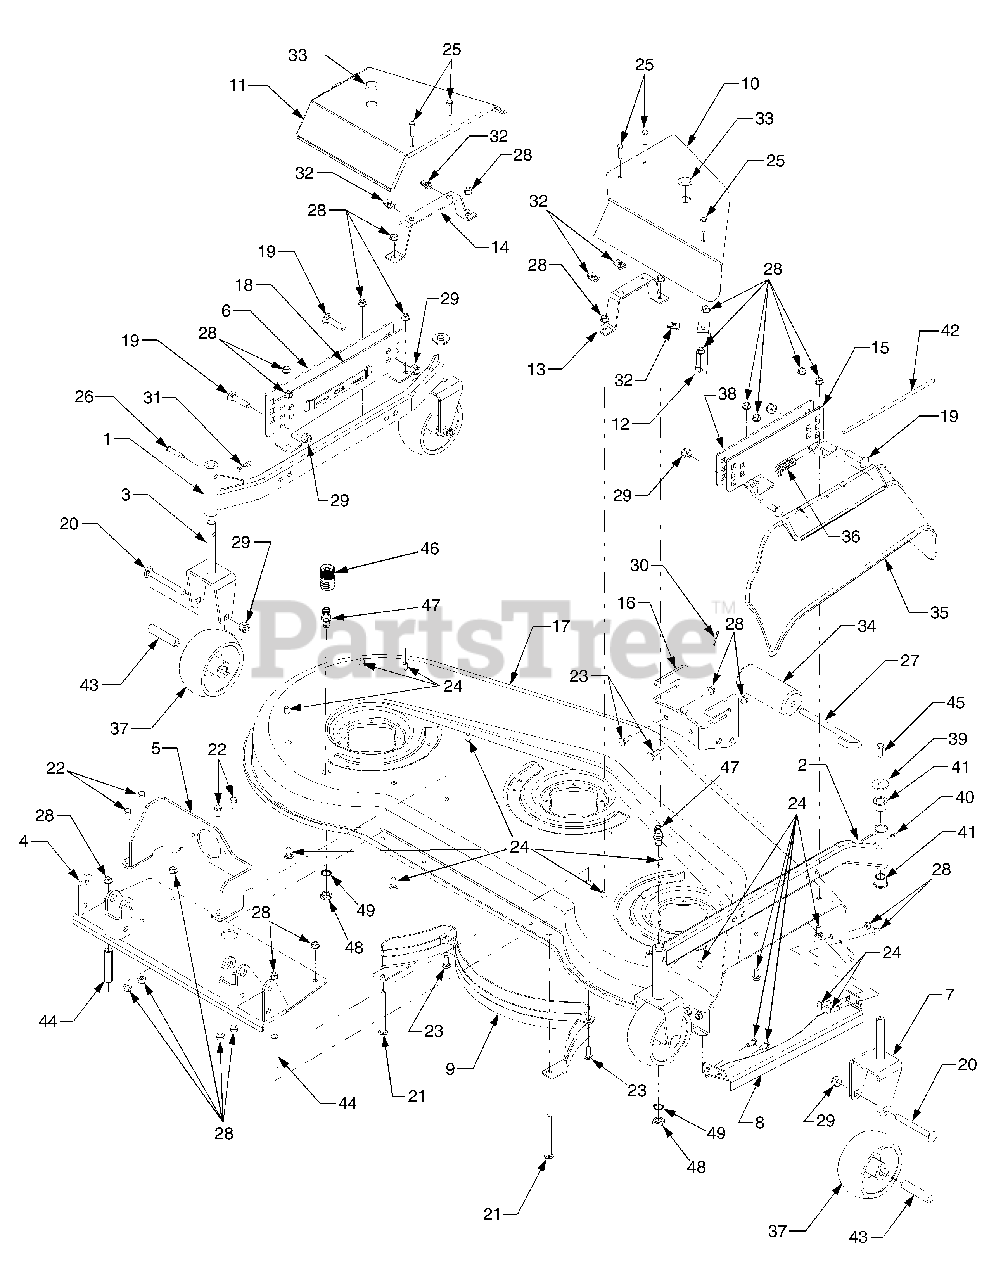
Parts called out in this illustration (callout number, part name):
1	Axle, Caster, LH
2	Axle, Caster, RH
3	Wheel Yoke, Rear
4	Bracket, Mounting
5	Bracket, Gear Box
6	Bracket, Caster LH Outer
7	Wheel Yoke, Front
8	Guard, Finger
9	Baffle, Rear Inner
10	Cover, Belt (R.H.)
11	Cover, Belt (L.H.)
12	Bracket, Belt Cover Mtg
13	Bracket, Belt Cover Mtg
14	Bracket, Belt Cover Mtg. LH
15	Bracket, Caster RH Outer
16	Bracket, Front Roller
17	Deck
20	Screw, Carriage 1/2-13 x 4.5 GR5
21	Screw, Carriage 3/8-16 x 4.50 GR5
22	Screw, Hex Cap Lock 3/8-16 x .88 GR5
23	Carriage, Bolt 3/8-16 x 1.0
24	Carriage, Bolt 3/8-16 x .75
25	Screw, Thumb Adjust 5/16-18 x 1
26	Pin, Clevis, 3/8 x 1.75
27	Pin, Roller 1/2 x 7.31
28	Nut, Flange Lock 3/8-16
29	Nut, Hex Nylon Lock 1/2-13 GR8
30	Pin, Cotter 1/8 x 1.0
31	Pin, Internal Cotter
32	Nut, "U" 5/16-18
33	Plug, Button
34	Roller, Front
35	Deflector, Chute
36	Spring, Torsion
37	Caster, Wheel w/Bearings
40	Fitting, Lube
41	Bearing, Flange, .754 ID
42	Rod, Deflector Chute
43	Axle, Caster Wheel
44	Spacer, .505 x .75 x 3.31Lg
